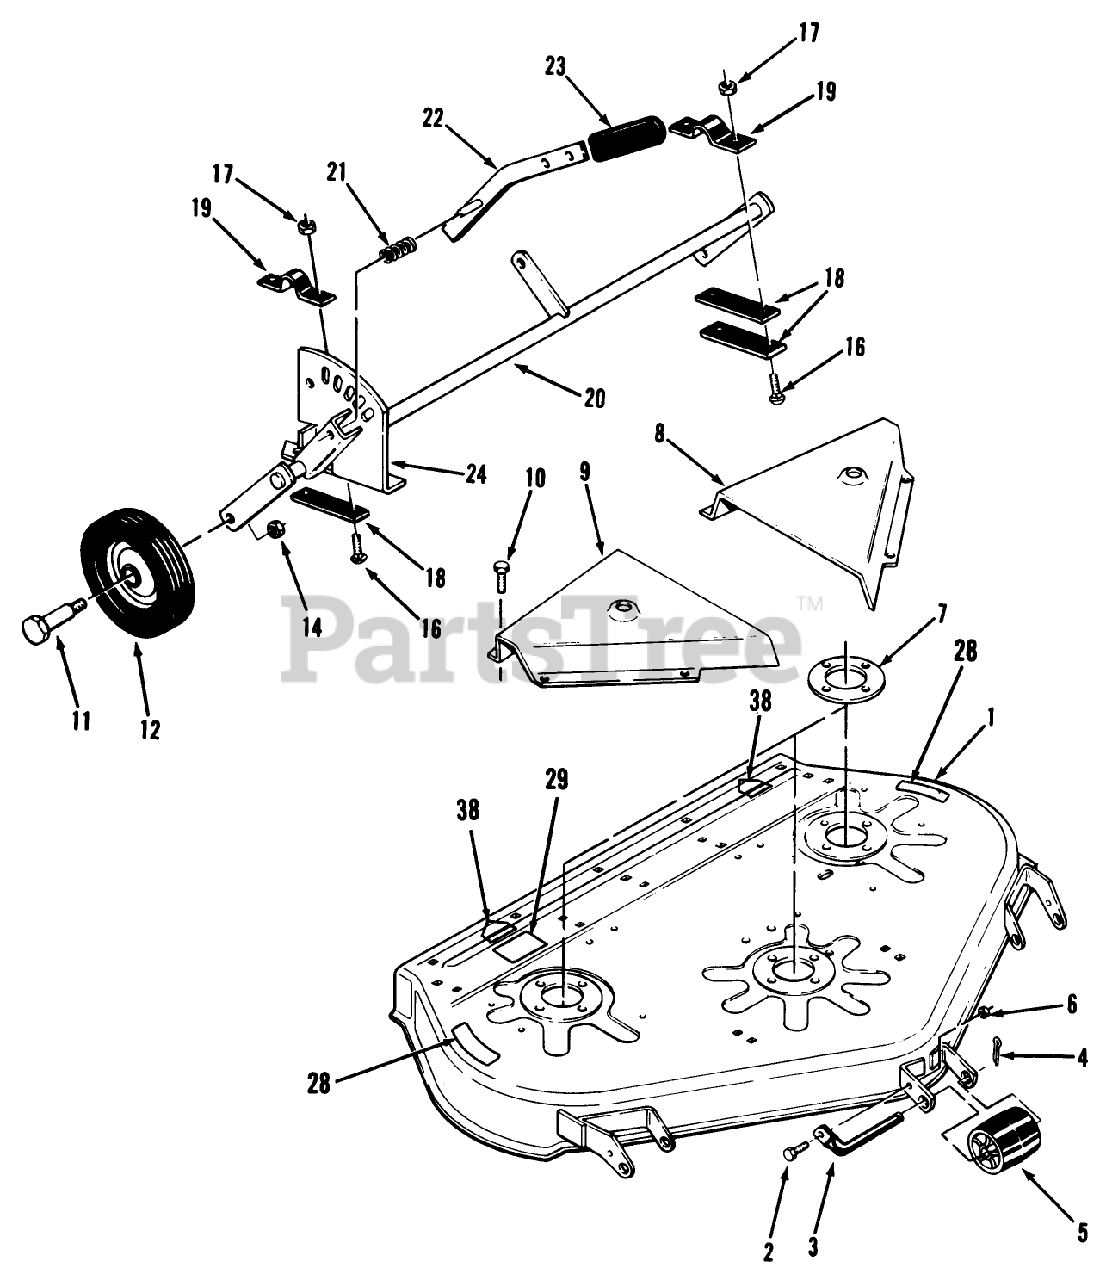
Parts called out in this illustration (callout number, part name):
2	Bolt
3	ROLLER-SHAFT
4	PIN-COTTER
6	NUT-LOCK, NI
7	PLATE-SPINDLE
10	Bolt
11	BOLT-SHOULDER
12	WHEEL
14	NUT-HEX
16	BOLT-CARR
17	NUT-LOCK, NI
19	CLAMP
21	SPRING-COMPRESSION
28	DECAL - DANGER
29	DECAL-HEIGHT & BELT
38	Decal-Danger
